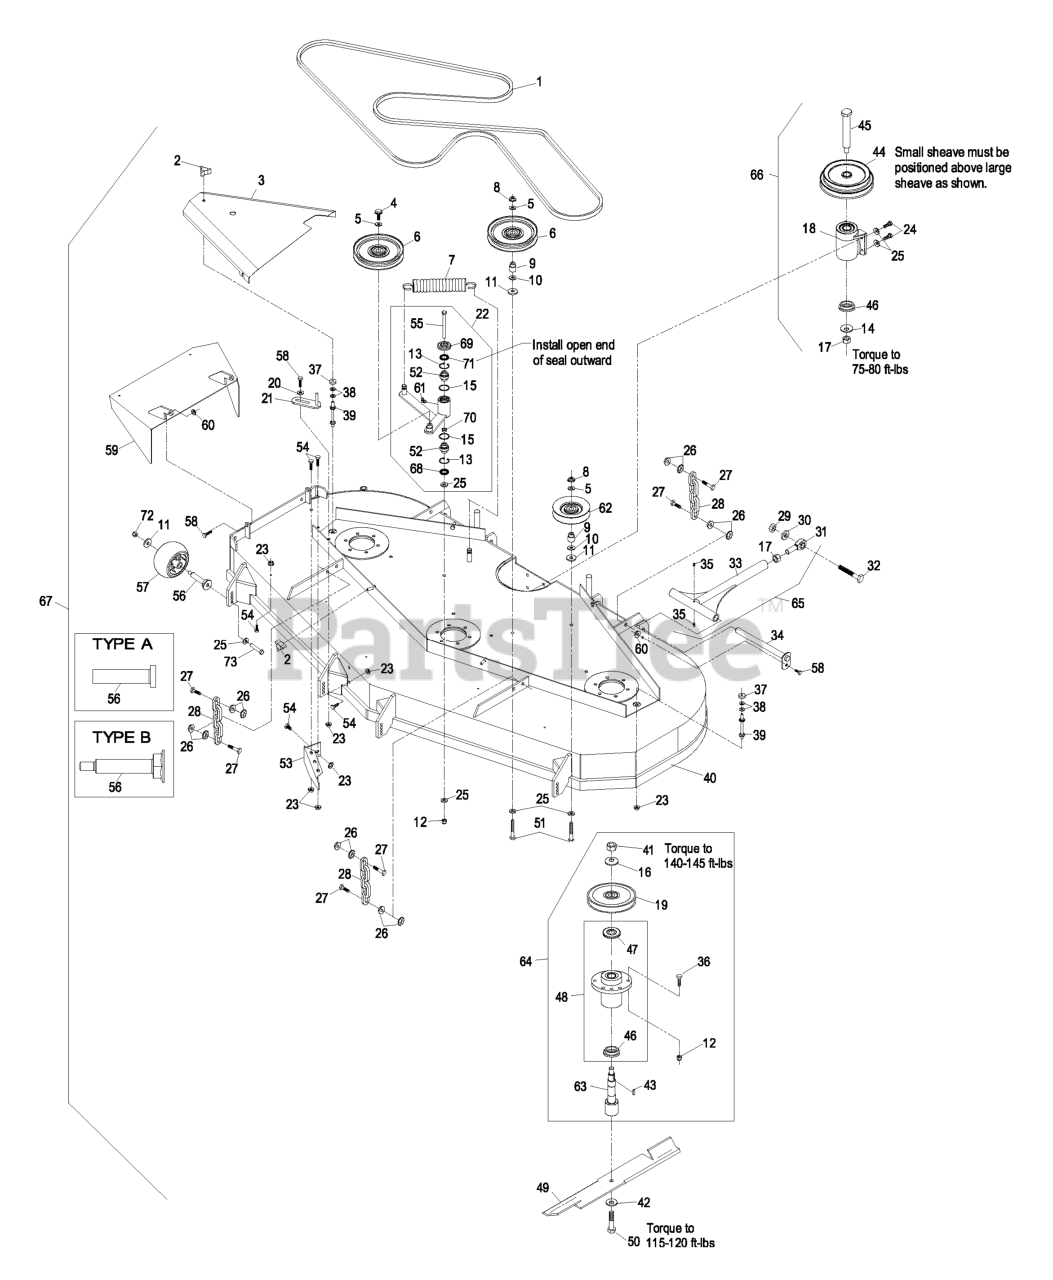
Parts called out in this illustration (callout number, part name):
1	BELT-V
2	KNOB-3 PRONG
3	SHIELD,BELT RH
4	SCREW-HHF
5	WASHER-FLAT
8	NUT-HHF, WHIZ
9	BUSHING-IDLER
10	WASHER-FLAT
12	NUT-LOCK, NI
13	RING-SNAP
14	WASHER-SPRING
17	NUT-HEX
19	SHEAVE,BLADE DRIVE 7.5
20	WASHER-SPRING
21	GUIDE-BELT
22	KIT,DECK IDLER LZ/XP
24	SCREW-HH
25	WASHER-BELLEVILLE
27	SCREW-HH
28	CHAIN-LIFT, DECK
29	NUT-HEX
30	WASHER-LOCK
31	BALLJOINT-SPHERICAL
32	SCREW-HH
34	PIN-STRUT
35	FITTING-GREASE
36	SCREW-HH
38	WASHER-FLAT
39	STUD-SHIELD, BELT (SHORT)
40	ASM,DECK W/DECALS LZ/XP72
41	NUT-HH
42	WASHER-BLADE BOLT, HEAVY
44	SHEAVE, JACKSHAFT DOUBLE
45	JACKSHAFT
46	SPACER-GUARD, BOTTOM
47	GUARD-BEARING, TOP
48	KIT, CUTTER HOUSING
50	SCREW-CAP
51	SCREW-HH
52	BEARING-SPHERICAL
53	WLD,BAFFLE DISCHARGE
54	SCREW-HH
55	SCREW-HH
56	BUSHING-ROLLER
57	ROLLER-SCALP, ANTI
58	SCREW-HH
59	WLD,CHUTE 72
60	NUT-LOCK, NI
61	FITTING-GREASE, 90 DEG
62	PULLEY-IDLER
63	SPINDLE,SHORT
64	ASM, CUTTER HSG COPL 72
65	ASM,STRUT 72 LONG
66	KIT,JACKSHAFT 60/72-3750
67	Complete Deck Asm
68	SEAL-LIP, DOUBLE
69	GUARD-TOP
71	SEAL-LIP, SINGLE
72	NUT-HHF, WHIZ
73	SCREW-HH
